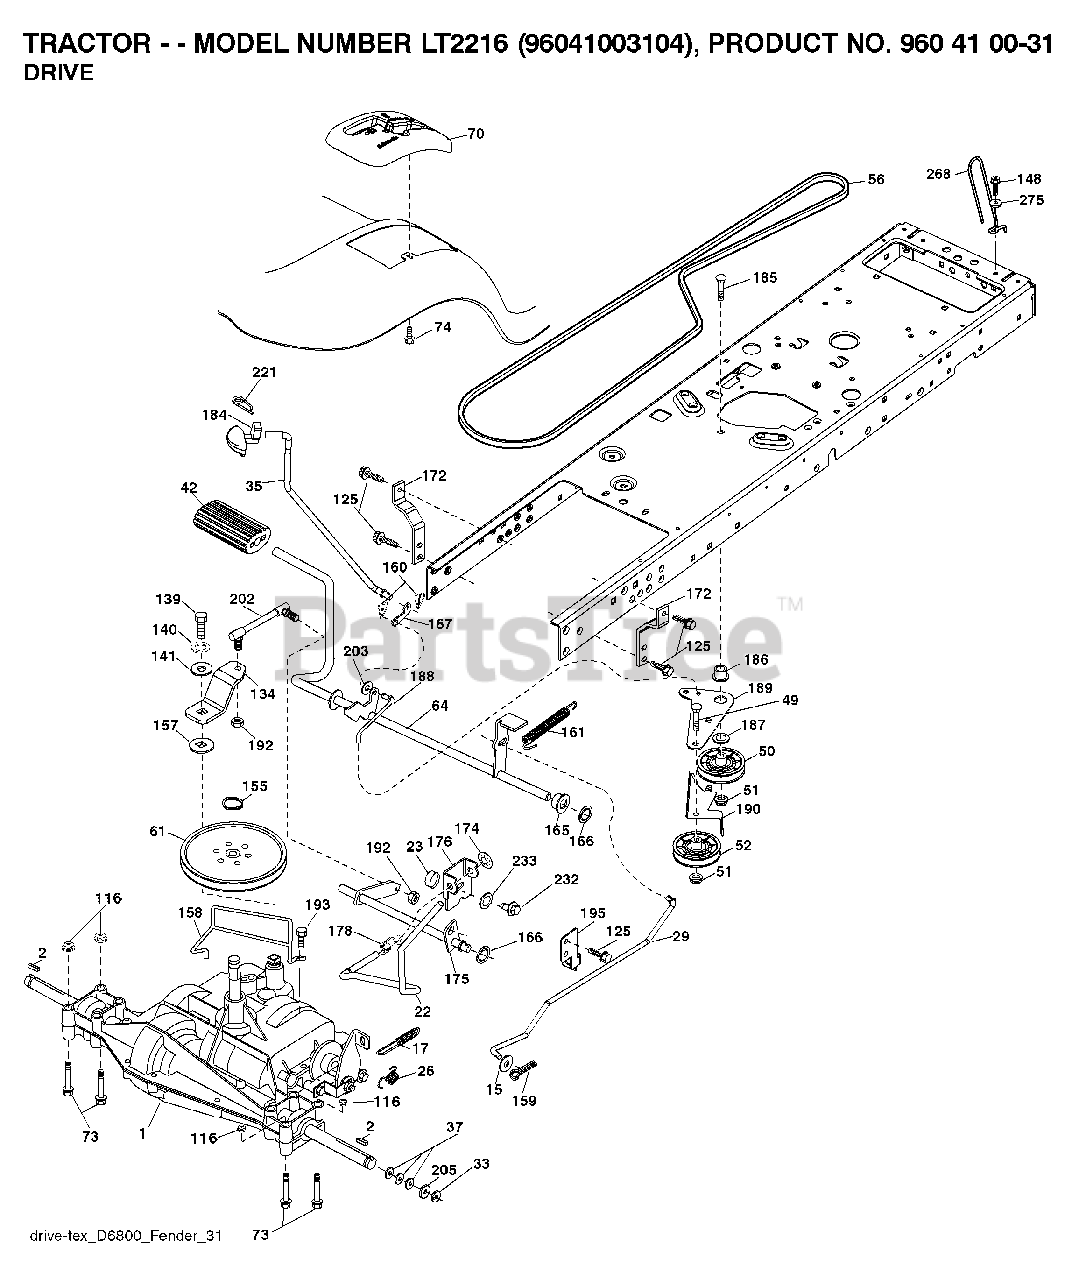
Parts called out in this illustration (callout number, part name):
2	SQUARE KEY
17	SPRING.BRAKE.PEERLESS.TEX
22	ROD.SHIFT.FENDER.TLT.2006
23	KNOB.DUCKHEAD.1/2
26	SPRING.BRAKE.RTN.GR.DR
29	ROD.BRAKE.PEERLESS
33	E-RING LT
35	ROD.BRAKE.PARKING.LT.T
42	PEDAL COVER T
49	BOLT
50	IDLER.FLAT.910.OFFSET
51	NUT LOCK FLG 3/8-16 UNC
52	IDLER.V-GROOVE.910.OFFSET
61	PULLEY TRANS
64	SHAFT.ASM.PEDAL.BRAKE.
70	CONSOLE.SHIFT.
73	BOLT HEX 5/16-18 GR 5
74	SCREW.HI-LO.CONSOLE
116	NUT LOCK HEX FLANGE 5/16-18
125	SCREW
134	ARM.SHIFT.
139	BOLT 1/4-28X3/4
140	LOCKWASHER
141	WASHER LT
148	SCREW, 3/8-16X3/4
155	RETAINING RING LT
157	WASH-SHFT PLT LT
158	KEEPER.PMS.18/20.D4365
159	COTTER PIN
160	RETAINER CLIP
161	SPRING.RETURN.CLUTCH.2006
162	SPACER.TRANSAXLE.18&22
165	BUSHING.SHAFT.BRAKE.HAND
166	NUT.PUSH.625.2006
167	LATCH.BRAKE.SPRING
172	STRAP.TRQ.LH.GEAR.DRIV
174	NUT.PUSH.500.2006
175	SHAFT.ASM.SHIFT.
176	ARM.CLEVIS.ROD.SHIFT
178	SPRING.SHIFT.GT2006
184	HANDLE.PAKRING.BRAKE.
186	SPACER.RETAINER
187	WASHER 12/32X2X10GA
188	LINK.CLUTCH.GROUND.DRIVE
189	BELLCRANK.GROUND.DRIVE.TEX.
190	KEEPER.BELLCRANK.DRIVE
192	NUT LOCK CENTER 1/4 -28 FNTHD
193	SCREW 5/16"
195	BRKT.ROD.BRAKE.PEERLES
202	LINK.TRANSAXLE.
203	WASHER
221	RETAINER.SPRING.CLIP.H
232	BOLT FIN HEX 7/16-14 X 1
233	WASHER SERRATED
268	WASHER
